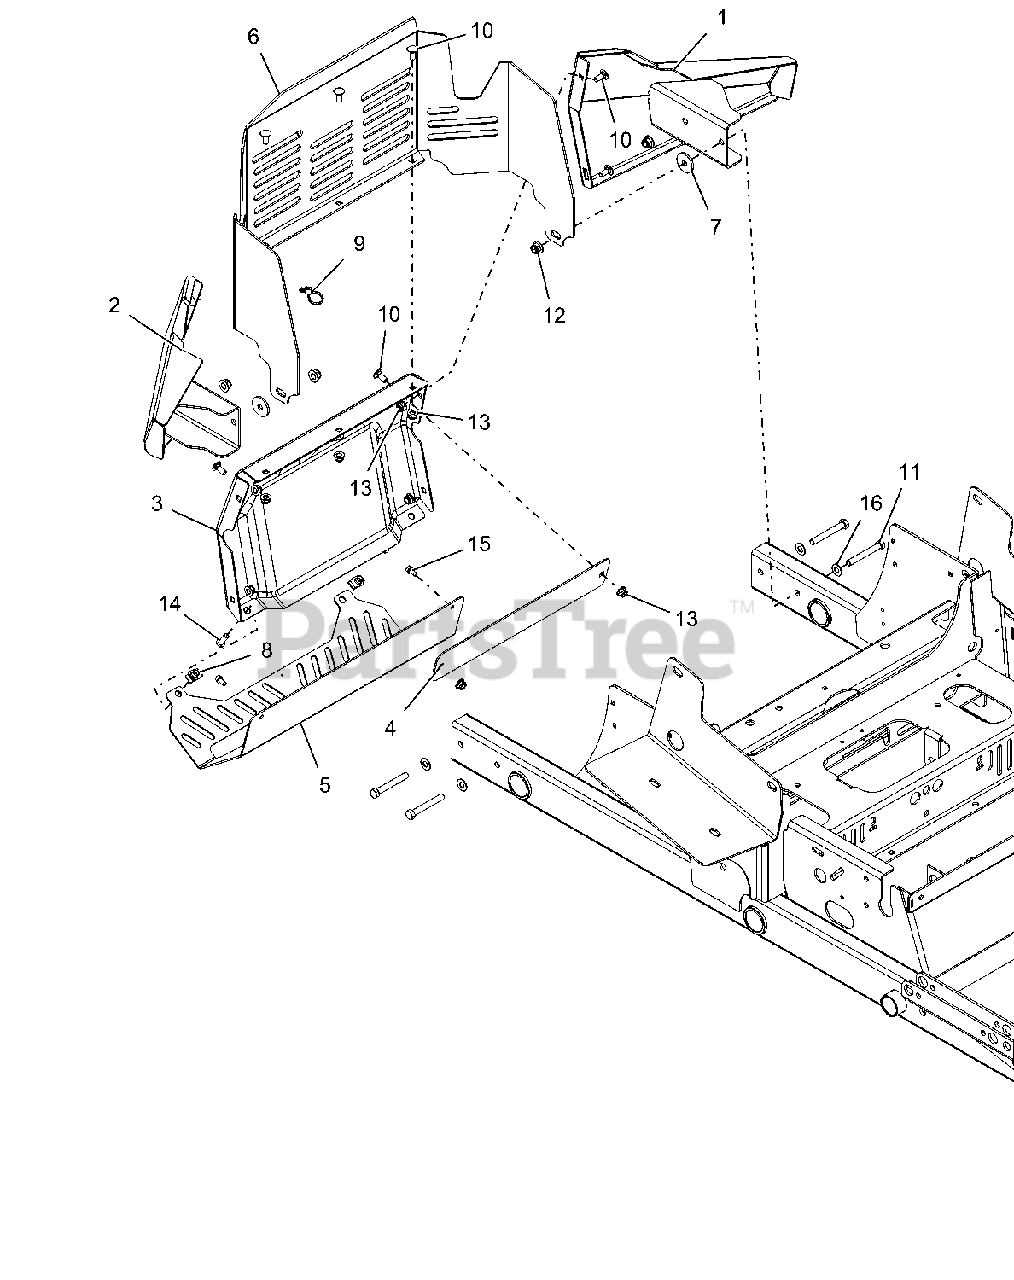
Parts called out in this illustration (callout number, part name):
1	LEFT REAR BUMPER WING WMT-BLK
2	RIGHT REAR BUMPER WING WMT-BLK
3	PT200/400 REAR BUMPER - BLACK
4	BACKER PLATE - RED
5	PT200/400 MUFFLER GUARD - BLK
6	PT200 ENGINE GUARD - RED
7	WSHR-FL-STL .406X1.375X.135 YZ
8	NUT-CLIP RETAINER 5/16-18X.56
9	CABLE TIE W/ TREE (.25 HOLE)
10	@BLT-RDHDSQNK .31-18X.75 G5YZ
11	@BLT-HEX .38-16X2.75 GR5 YWZC
12	@NUT-LK-NYL-FLG .38-16 YWZC
13	@NUT-LK-NYL-FLG .31-18 YWZC
14	SCR-SKH .31-18X1.0 BTNHD YWZC
15	SCR-TAP .25-20X.50 HWH TR YWZ
16	@WSHR-FL-STL.406X.812X.065 YWZ
